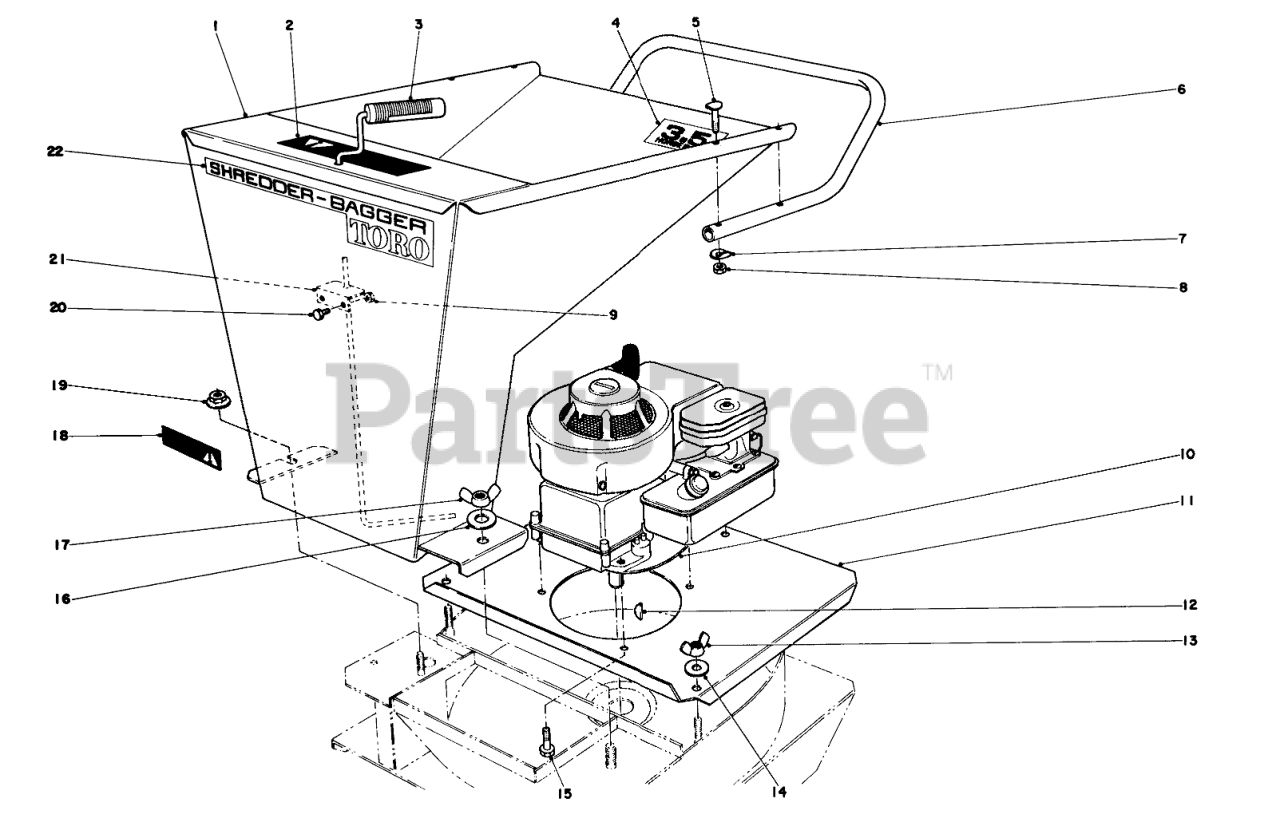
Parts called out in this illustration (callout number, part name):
1	Hopper
2	Caution Decal
3	Feeder rod
4	Decal, 3.5 HP
5	HANDLE SCREW
6	Handle
7	WASHER
8	NUT-HEX
9	Nut
10	Engine
11	Base plate
12	KEY-WOODRUFF
13	Wing nut
14	WASHER-LOCK
15	SCREW-HWHTF
16	WASHER-FLAT
17	Wing nut
18	Decal-warning
19	FLANGE NUT W/LG FLG
20	SCREW-HH
21	Clip-rod
22	Decal,logo
